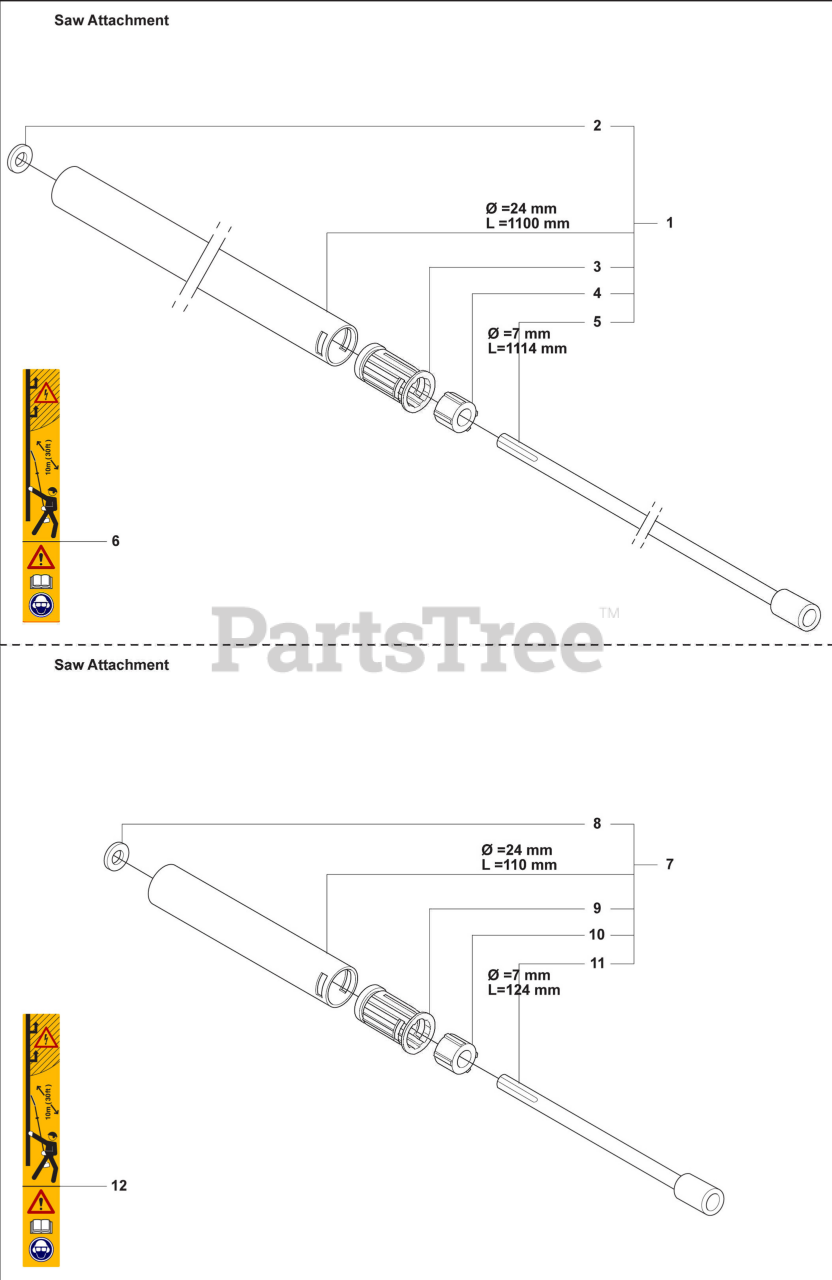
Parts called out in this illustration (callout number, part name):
1	Tube
4	Bushing
5	Drive Shaft
7	TUBE
10	Bushing
11	Shaft
